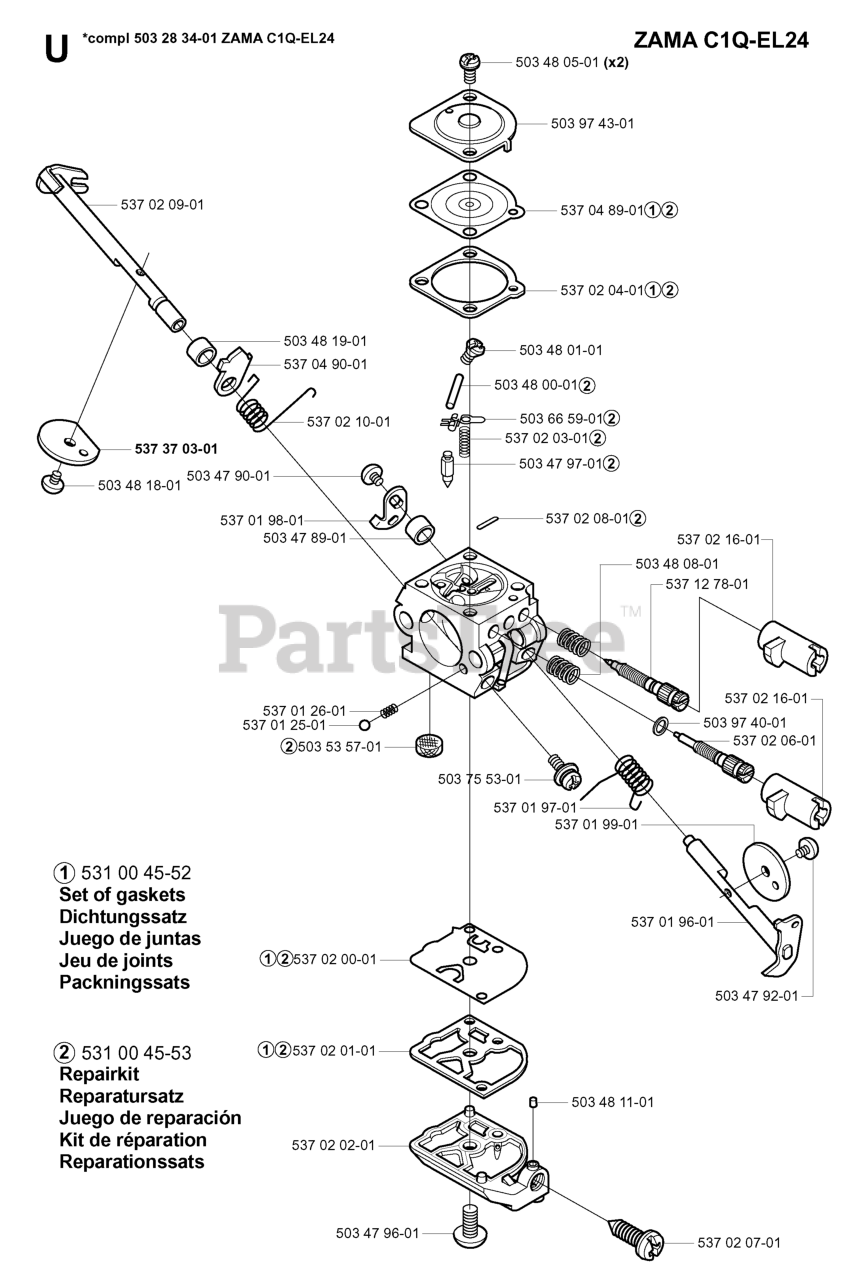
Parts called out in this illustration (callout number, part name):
1	DRIFT CUTTER BAR
2	WASHER, NYLON FRICTION
3	BOLT
4	WASHER.LOCK.HVY.HLCL.SPR.5/16
5	NUT WING PM
